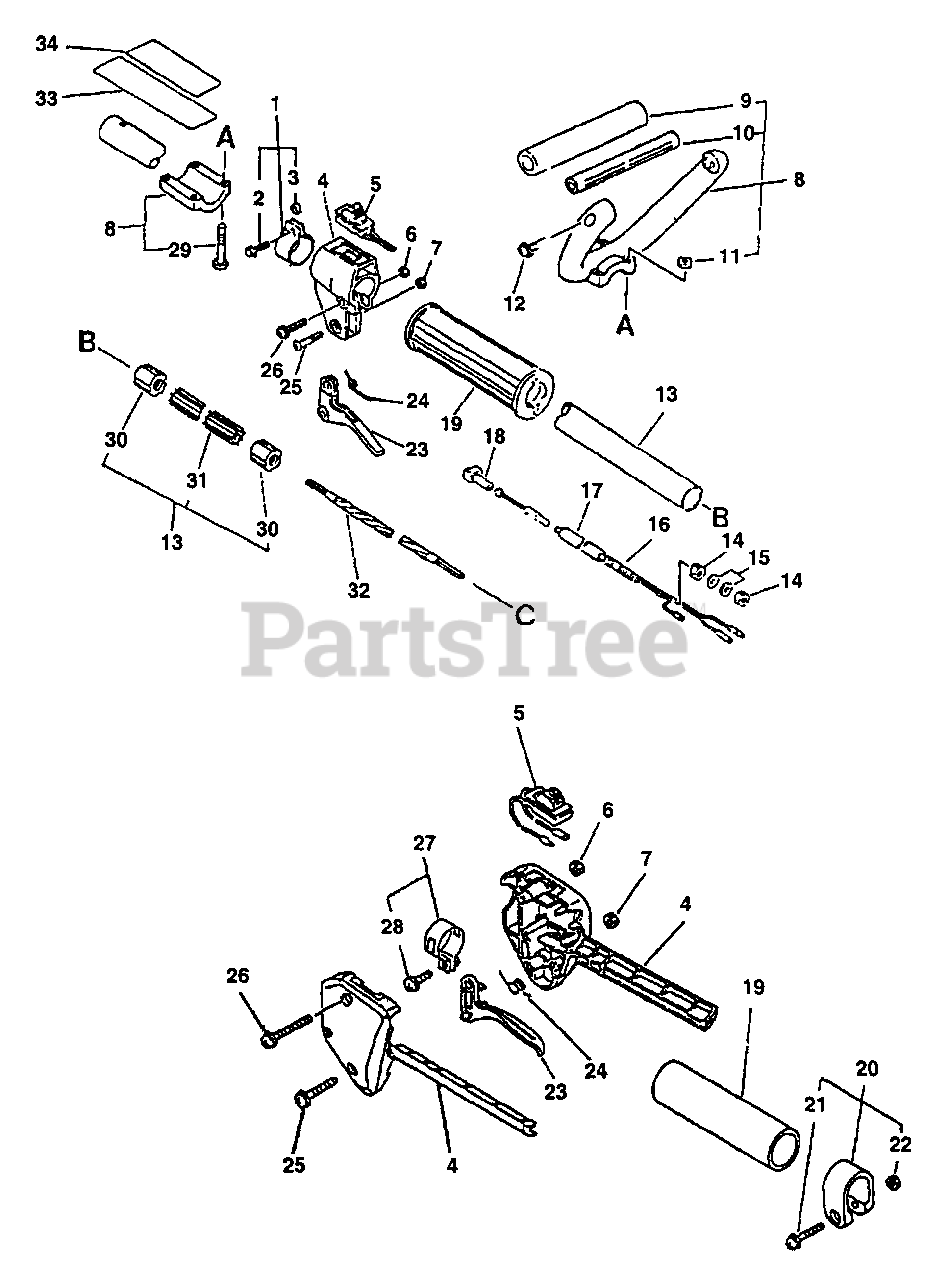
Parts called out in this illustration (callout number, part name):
1	HOOK
2	BOLT 5×18
3	SPACER, GUARD
4	BRACKET, THROTTLE CONTROL
4	HANDLE KIT, CONTROL
5	IGNITION SWITCH ASSY
6	NUT M5
7	NUT, LOCK M5
8	LOOP HANDLE ASSY
9	GRIP, HANDLE
11	NUT M5
12	SCREW 5×30
13	MAIN PIPE ASSY 25×1500
15	WASHER 6.5×11.5×0.8
16	CABLE, THROTTLE
17	PIPE
18	GUIDE, CABLE
19	GRIP
19	GRIP, HANDLE
20	CLAMP KIT
21	SCREW 5×28
22	NUT M5
23	TRIGGER, THROTTLE
24	SPRING, THROTTLE
24	SPRING, TORSION
25	SCREW
25	SCREW 5×25
26	SCREW 5×30
26	SCREW 5×35
27	CLAMP KIT
28	SCREW 5×14
29	SCREW 5×35
31	LINER, FLEXIBLE 21.6×1420
32	DRIVESHAFT - FLEXIBLE L= 1522
33	LABEL, CAUTION
34	LABEL, CAUTION
